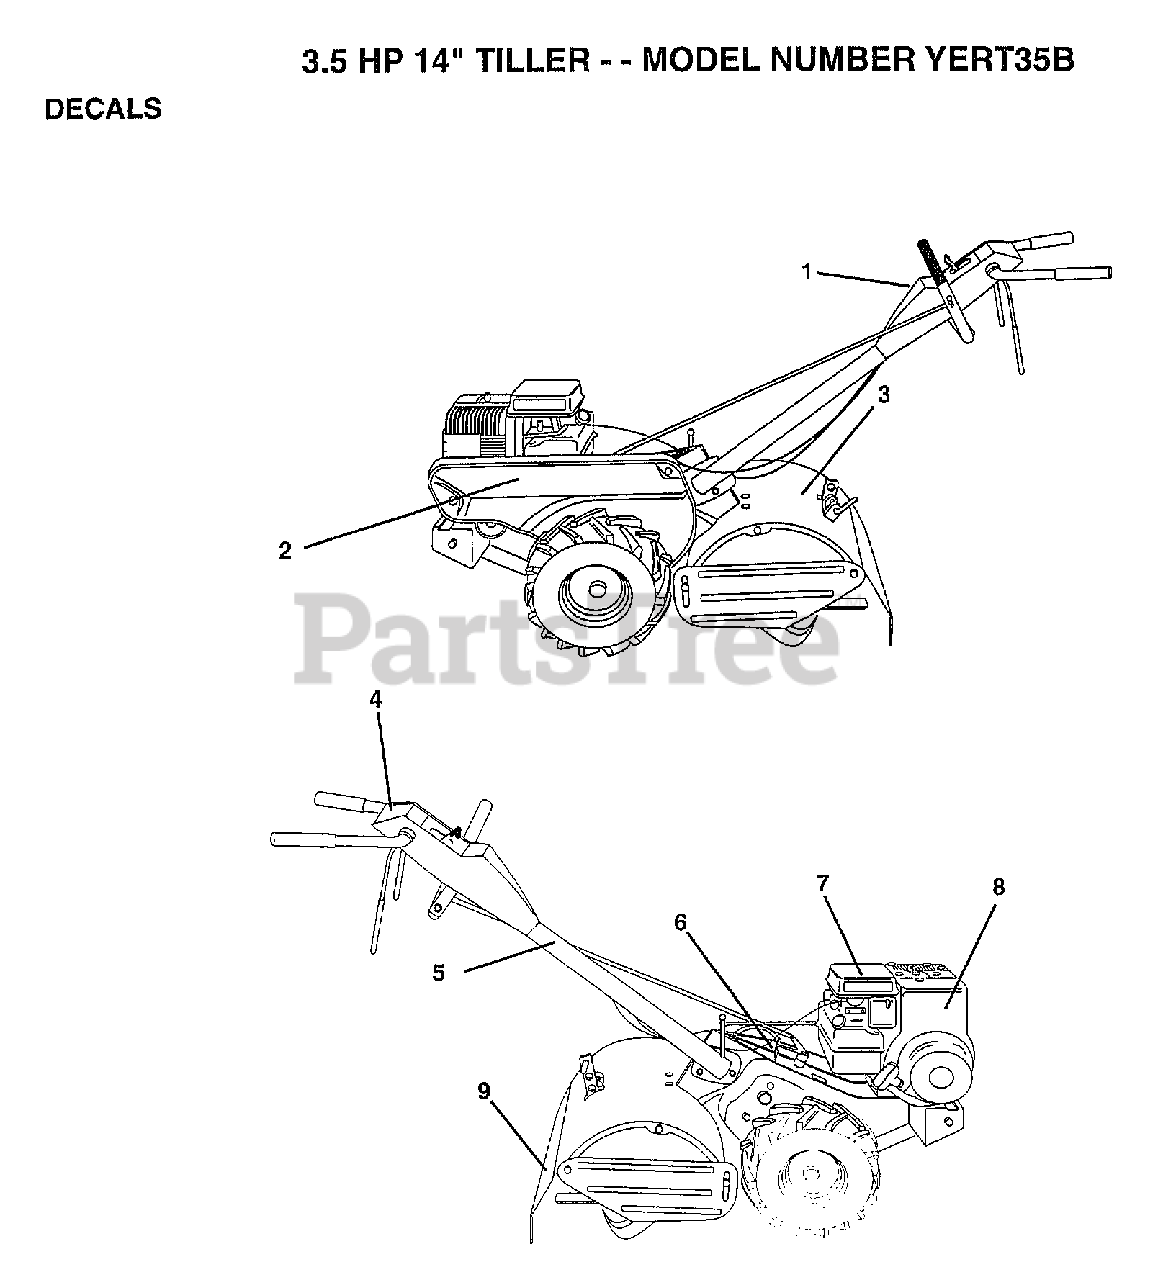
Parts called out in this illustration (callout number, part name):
1	DECAL.PNL.CONTROL
2	DECAL.GUARD.BELT
3	DECAL, LOGO
4	DECAL.INSTRUCTION
5	DECAL TI
7	DECAL TI
8	"DECAL,ENG HP"
